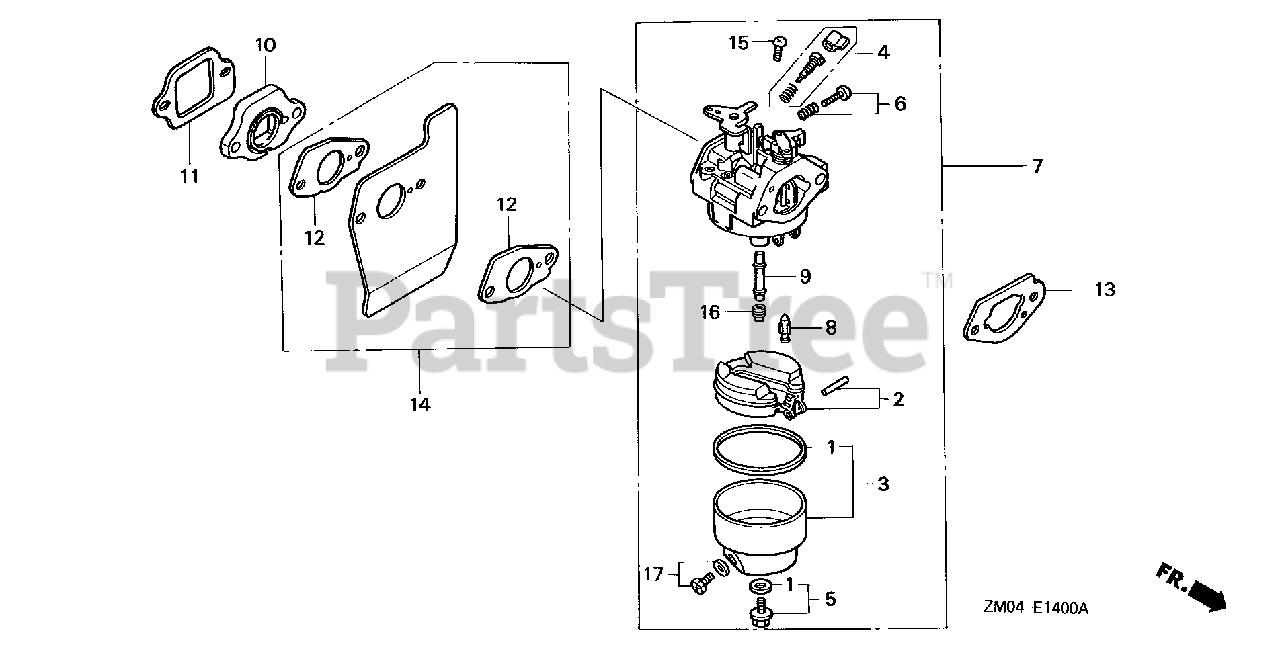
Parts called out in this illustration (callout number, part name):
1	GASKET SET
2	FLOAT SET
3	CHAMBER SET, FLOAT
4	SCREW SET
5	SCREW SET B
6	SCREW SET
7	CARBURETOR ASSY. (BB62B D)
8	VALVE, FLOAT
9	NOZZLE, MAIN
10	INSULATOR, CARBURETOR
11	GASKET, INSULATOR
12	GASKET, CARBURETOR
13	GASKET, CARBURETOR (CHOKE SIDE)
14	GUIDE, AIR
15	SCREW, PAN (5X6)
16	JET, MAIN (#60)
16	JET, MAIN (#62)
16	JET, MAIN (#65)
17	SCREW SET, DRAIN
